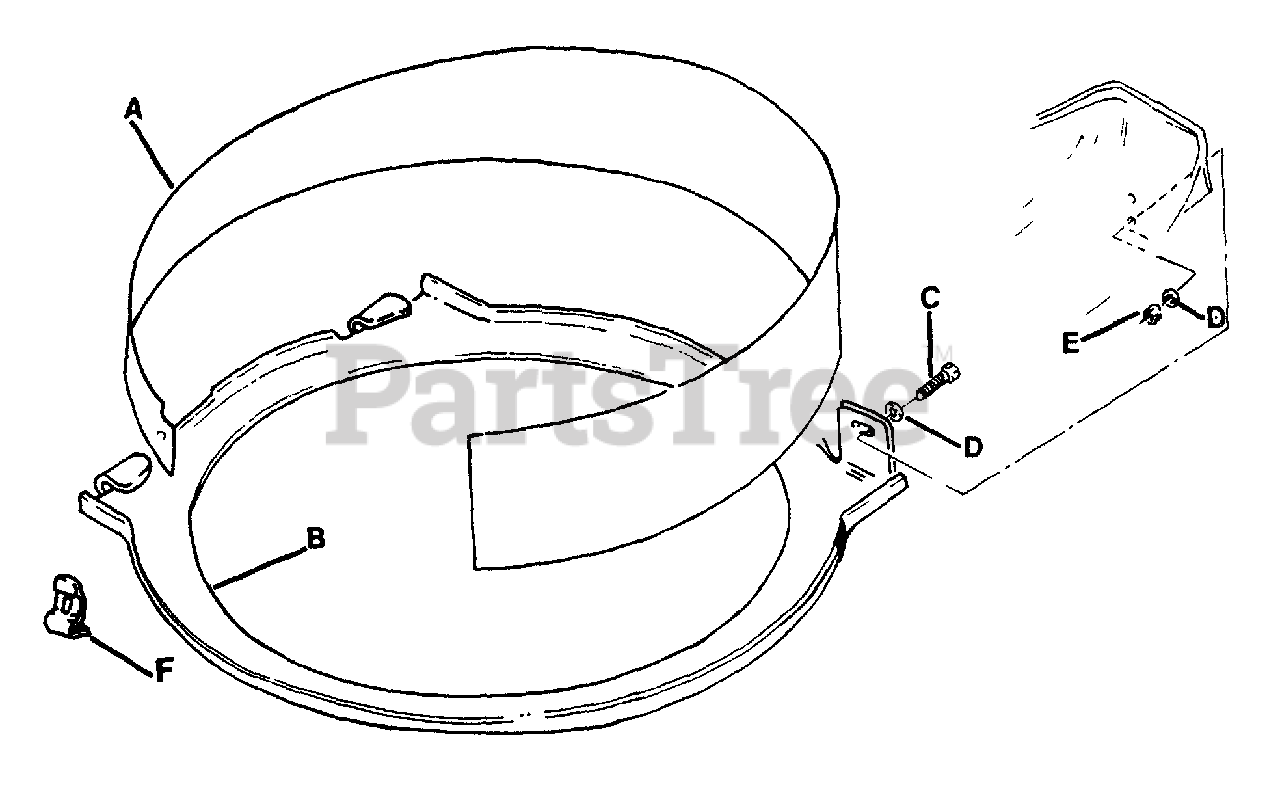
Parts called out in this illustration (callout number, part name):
A	LINER, CV DECK
B	PLATE, BOTTOM
C	SCREW, HEX HEAD CAP 1/4-28 x 3/4
D	WASHER, SPLIT LOCK 1/4
E	NUT, HEX 1/4-28
F	MOUNT, BOTTOM PLATE
